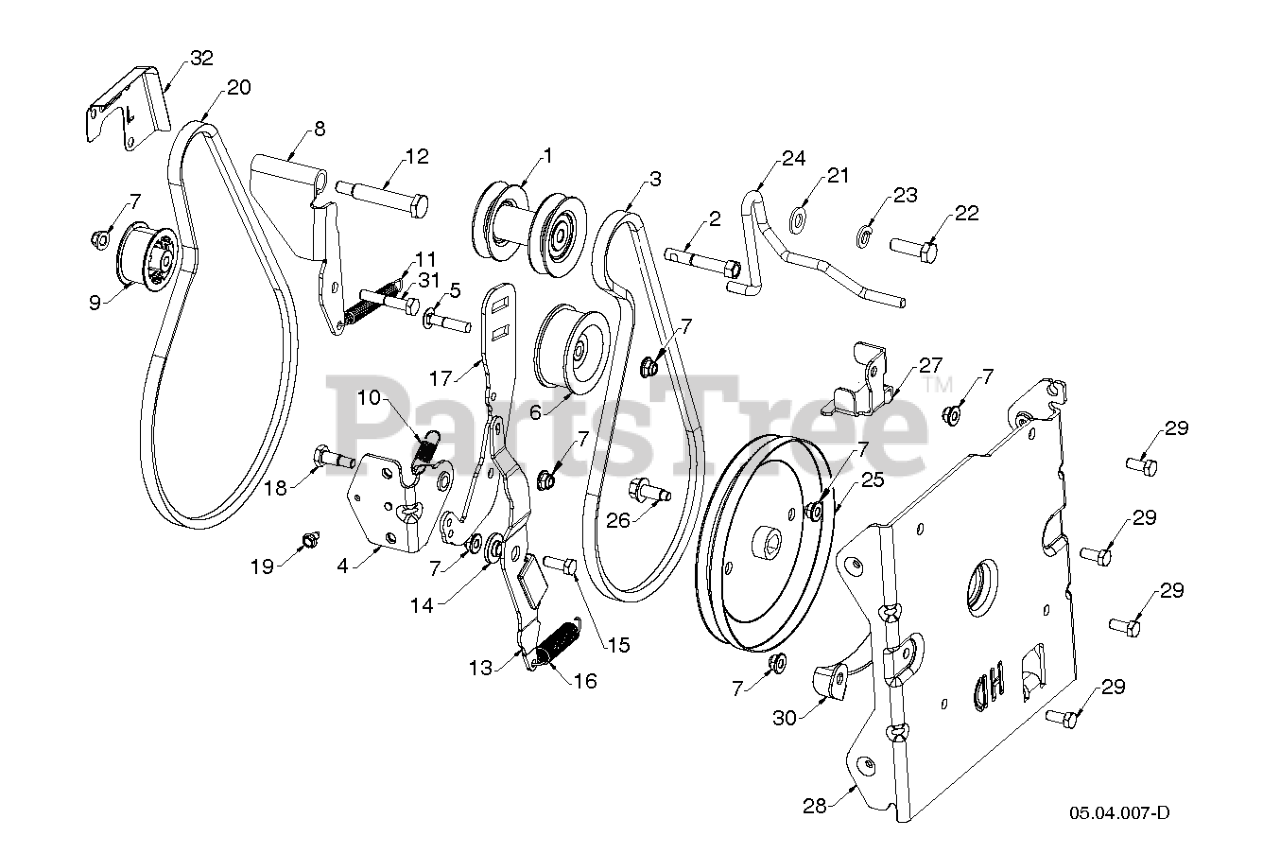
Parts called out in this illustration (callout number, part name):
2	BOLT.ENGINE.PULLEY
3	LOW CRANK IMPELLER BELT
4	BRACKET WELDMENT, IDLER ARM ZI
5	BOLT 5/16-18 CARRIAGE 1.5L
7	NUT HEXAGON FLANGE 5/16-18 ST
8	ARM DRIVE IDLER CLEAR ZINC PLA
9	PULLEYIDLER.2.0.W/SPACER.CZ
10	SPRING IDLER RETURN
11	SPRING RETURN IDLER ARM
12	BOLT 5/16-24X2.25 HEX HEAD SHO
13	ARM IMPELLER BRAKE
14	BUSHING.BRAKE.ARM
15	BOLT HEXAGON BOLT 5/16-18 X 7/
16	SPRING EXTENSION - BRAKE
17	ARM IDLER BLACK ZINC
18	SCREW HEX HEAD SHOULDER
21	WASHER 11/32 X 11/16 X 14 GA T
23	WASHER SPRING LOCK WASHER WITH
24	Belt Keepers
25	PULLEY IMPELLER DD 4L HD
26	SCREW HEXAGON HEAD FLANGE 3/8-
27	GUIDE.LOWER.AUGER.BELT.479
28	BRACKET AUGER HOUSING INTERFAC
29	SCREW HEXAGON HEAD SCREW 5/16-
30	BRACKET.BELT.KEEPER.LOWER.BLAC
31	BOLT, HEX 5/16-18X1-3/4
